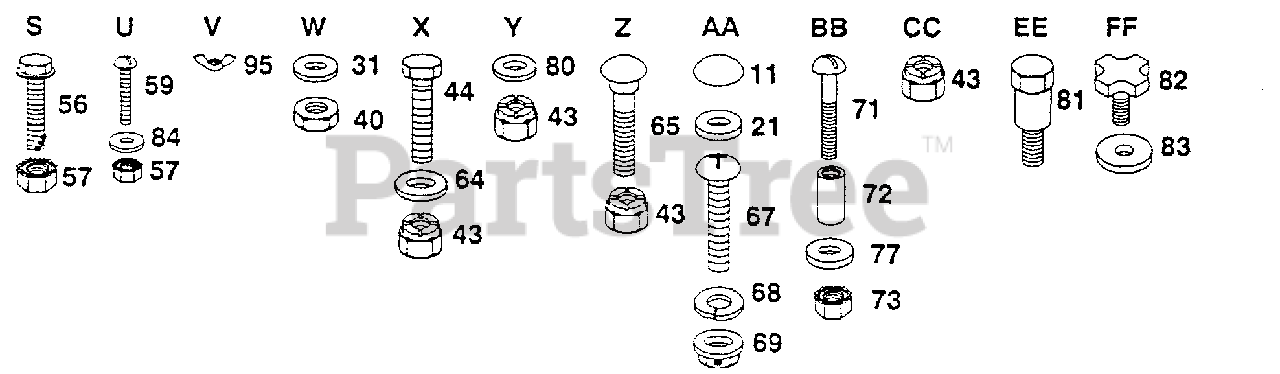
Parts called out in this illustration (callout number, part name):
21	Washer, Snap Cap
31	Washer 9/32 x 3/4 x 16 Ga.
40	Nut, Hex 1/4-20
43	Nut, Crownlock 3/8-16
44	Bolt, Hex 3/8-16 x 1
56	Bolt, Hex 5/16-18 x 3/4 Gr. 5
57	Nut, Keps 5/16-18
58	Bracket Assembly, Fender
59	Screw, Truss Hd. 5/16-18 x 3/4
64	Washer 13/32 x 1-1/4 x 12 Ga.
65	Bolt, Carriage 3/8-16 x 3/4
67	Screw, Cross Recess Pan Hd. Mach. #10-24 x 1/2
69	Nut, Weld
71	Screw, Machine Cross Recess #10-24 x 1-1/4
72	Spacer, Split #10 x 3/4
73	Nut, Keps #10 - 24
77	Washer 7/32 x 1/2 x 18 Ga.
80	Washer 13/32 x 1 x 14 Ga.
81	Bolt, Shoulder 5/16 x 18 UNC x .62
82	Knob-1/2
83	Washer 17/32 x 13/16 x 12 Ga.
84	Washer 11/32 x 11/16 x 16 Ga.
95	Wing Nut 1/4-20
